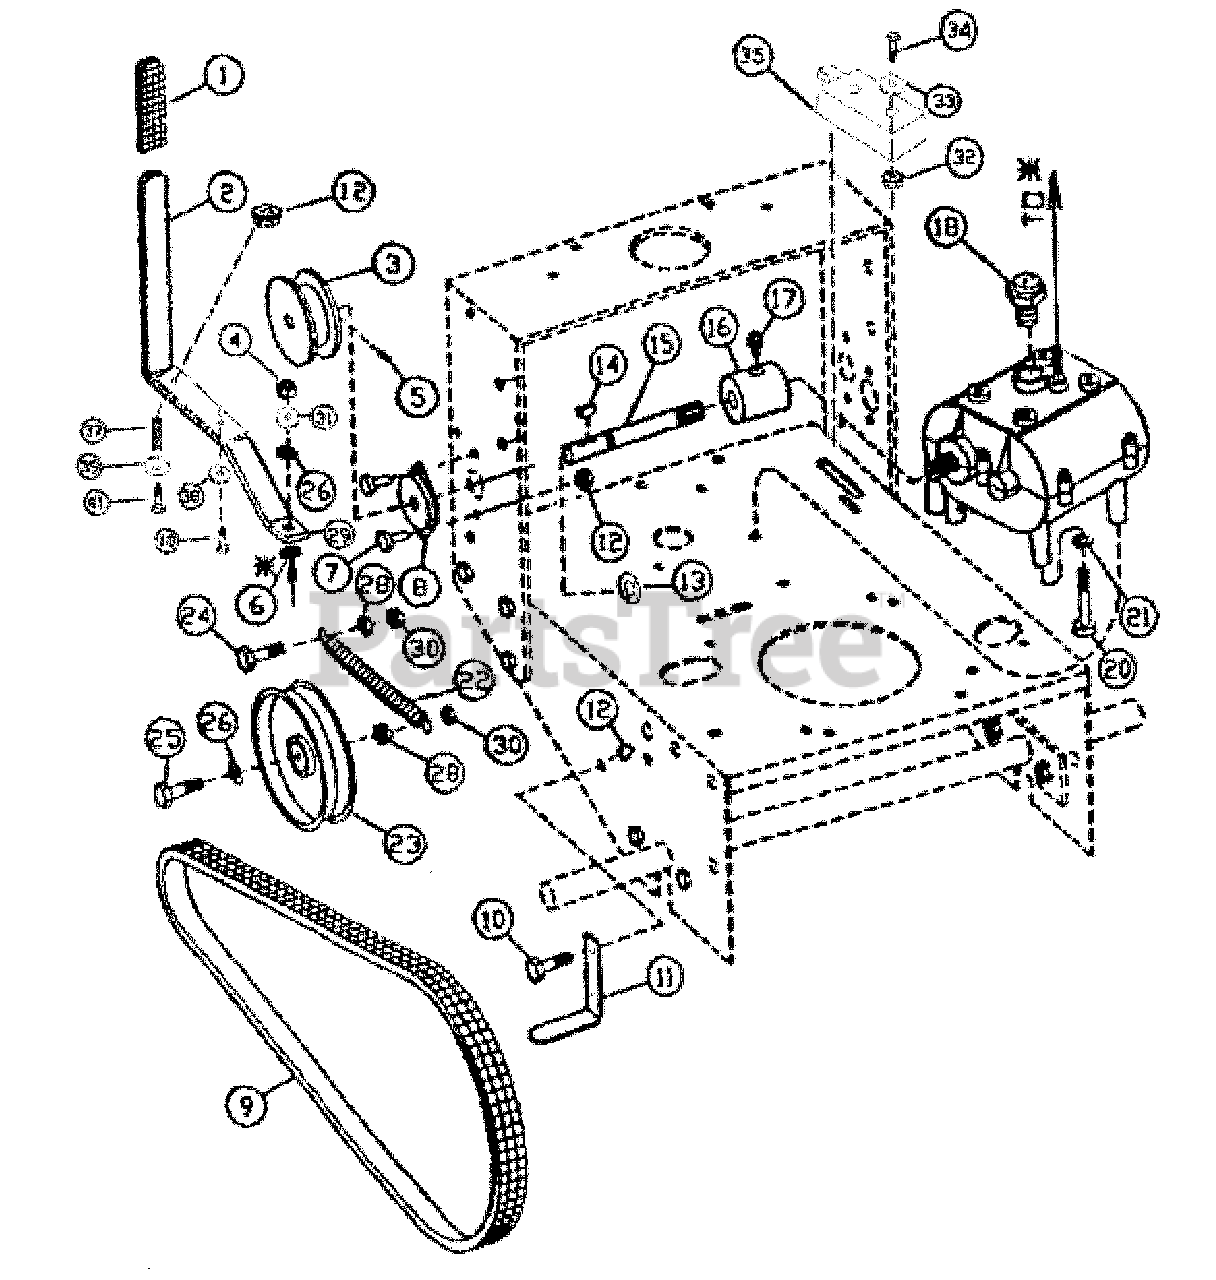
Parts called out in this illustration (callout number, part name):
1	100-045 FLAT GRIP
2	100-046 TRANS SHIFT LVR
3	100-047 OUTPUT PULLEY
4	200-034 NUT 3/8-24
5	200-035 SCREWS M8`10
7	200-011 BOLT M6`16
8	100-049 FLANGE BEARING
9	100-050 TRACTION BELT
10	200-036 HEX BOLT M6`20
11	100-051 BELT GUIDE
12	200-009 NYLON NUT M6
13	200-047 SNAP-RING -10 PACK
14	100-052 WOODRUFF KEY
15	OUTPUT SHAFT
16	100-054 COUPLING
17	GREASE FTG (10 PACK) 200-026
18	100-055 NEUTRAL SWITCH
20	200-037 HEX BOLT 5/16-18
21	5/16HELICAL L-WASHER
22	100-057 TRACTION SPRING
23	100-058 IDLER PULLEY
24	200-032 HEX BOLT M10`50
25	M10X1.5X60 HHB GR8.8
26	WASHER, 3/8 STD FLAT
28	200-016 NUT FLANGE M10
30	200-006 NYLON NUT M10
31	3/8HELICAL L-WASHER
32	200-039 NYLON NUT M4
33	200-040 PLAIN WASHER 4
35	100-060 SWITCH
37	100-061 COMP. SPRING
38	WASHER, 3/16 STD FLAT
39	200-043 PLAIN WASHER 6
41	200-044 HEX BOLT M6`40
